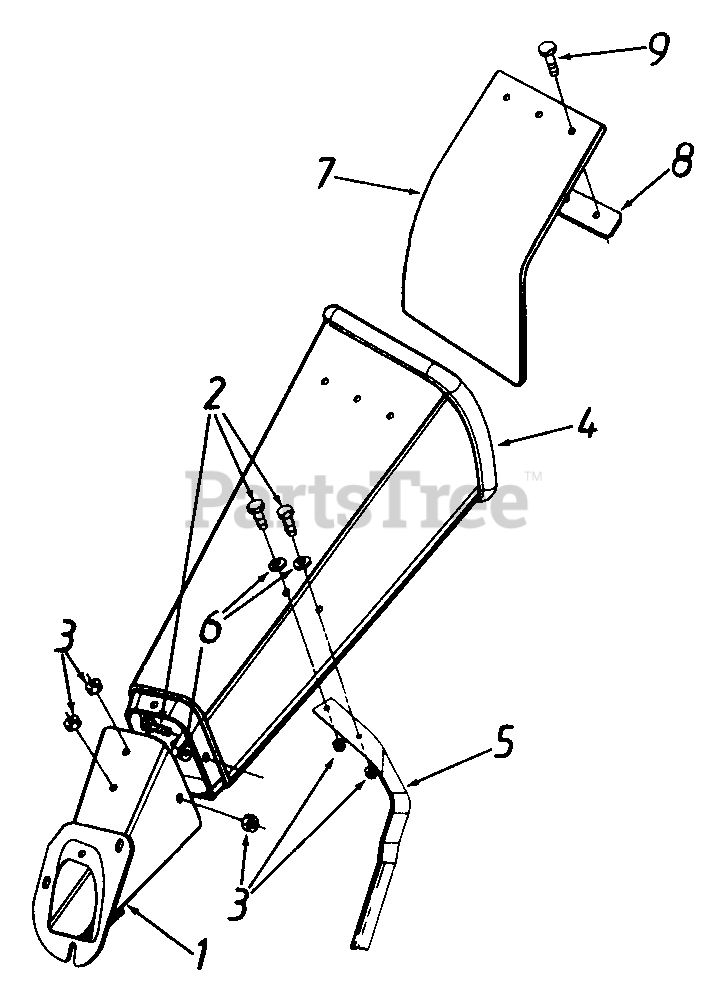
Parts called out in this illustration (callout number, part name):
3	NUT-LOCK
4	CHUTE -CHIPPER UPPER
5	FL-WASH..28" I.D. x .73" O.D.
8	STRIP-FLAP
